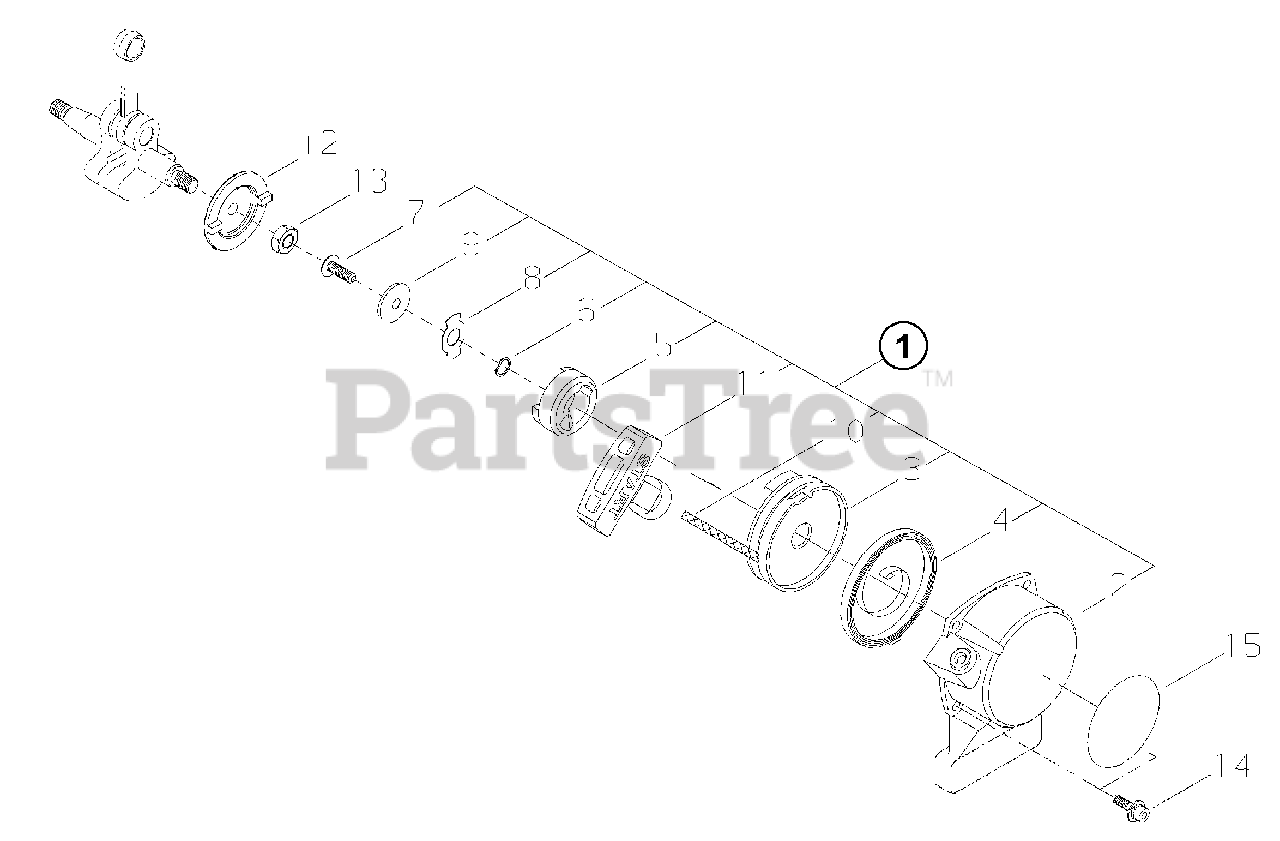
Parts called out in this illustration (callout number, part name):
1	STARTER ASSY
2	CASE, STARTER
3	REEL, ROPE
4	SPRING, REWIND
5	PAWL, STARTER
6	WASHER - SPRING
7	SCREW - 5
8	RETAINER
9	WASHER - 5
10	ROPE, STARTER
11	GRIP, STARTER
12	PAWL
13	NUT - 8
14	SCREW - 4X16
15	LABEL - C4
